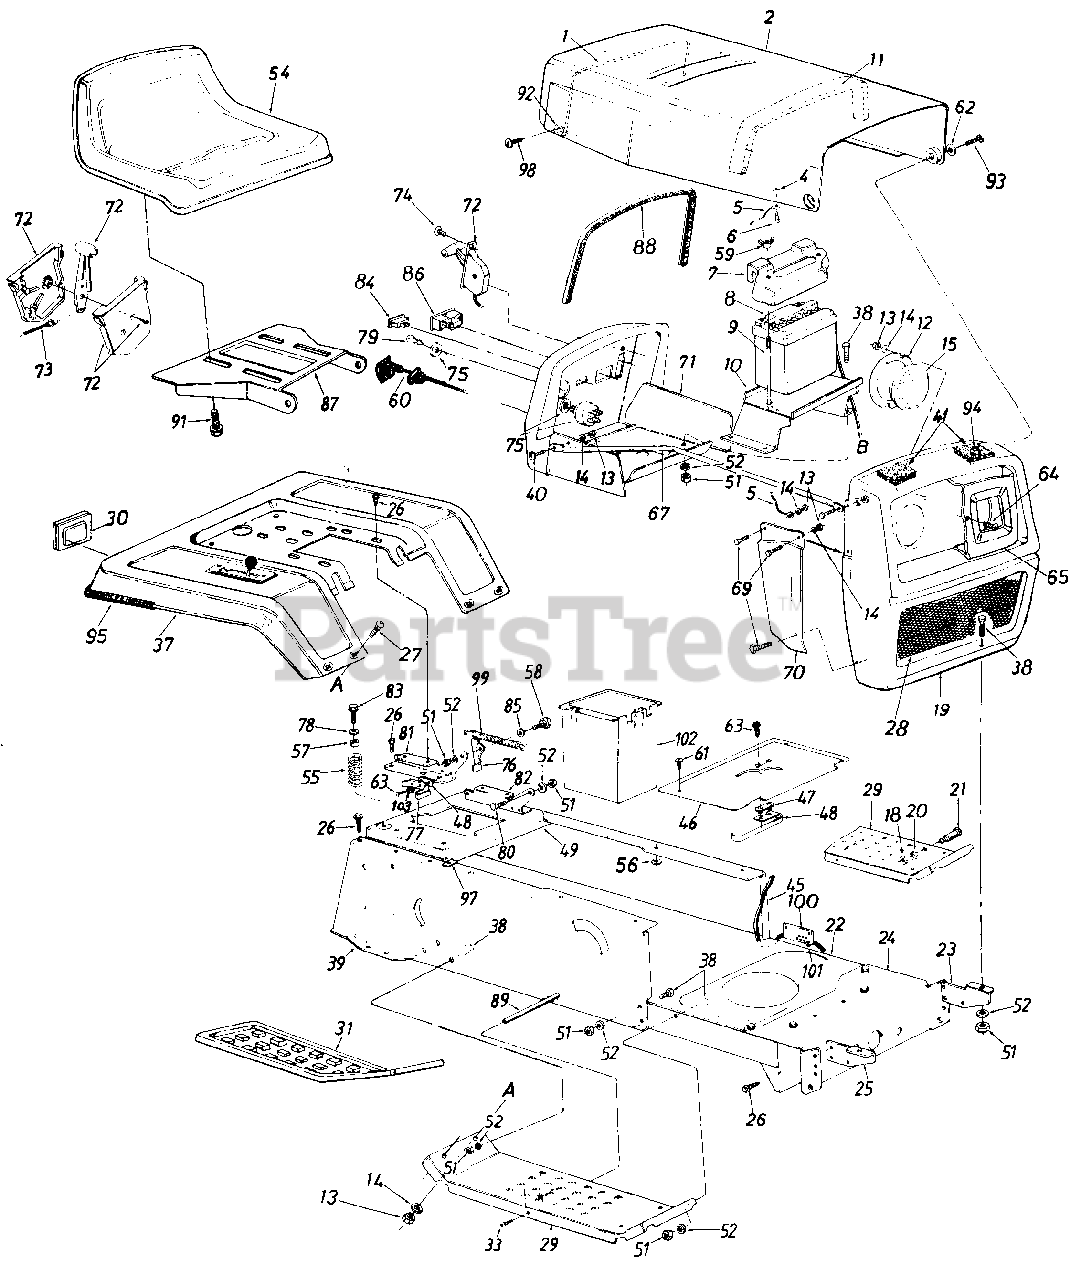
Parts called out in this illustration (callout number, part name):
1	Hood Spring
5	Hood Stop 7" Lg.
6	Pop Rivet
7	Battery Cover
8	12 Volt Battery
9	Battery Hold Down Rod
10	Battery Bracket
11	PVC Foam-Strip
12	Headlight Retainer
13	Hex Nut 14-20 Thd.
14	L-Wash 1/4" I.D.*
15	Headlight
18	Hex Nut 3/8-16 Thd.*
19	Grille Ass'y.
20	L-Wash. 3/8" I.D.*
21	Shld. Bolt .50" Dia. x .84
22	Lower Frame
23	Grille Mount Brkt.
24	Front Pivot Brkt.
25	Grille Mount Brkt.
26	Hex Wash. Hd. AB-Tap Scr. 5/16 x .75" Lg.
27	Carriage Bolt 1/4-20 x .5" Lg.*
28	Grille Insert
29	Running Board
30	Reflector
31	Foot Pad-L.H.
33	Truss Mach. Scr. 5/16-18 x .75" Lg.*
37	Fender
38	Hex Bolt 5/16-18 x .75" Lg.*
39	R.H. Side Frame
40	Hex Bolt 1/4-20 x .62" Lg.*
41	Foam Strip
45	L.H. Side Frame
46	Shift Cover
47	Reverse Safety Switch
48	Insulator Nut Plate
49	Hitch Plate
51	Hex Nut 5/16-18 Thd.*
52	L-Wash. 5/16" I.D.*
54	Seat Ass'y.
55	Compression Spring
56	Ext. L-Wash. 5/16" I.D.
57	Bushing
58	Shld. Bolt .437" Dia. x .268"
59	Wing Nut 1/4-20 Thd.-Plastic
60	Choke Control 46" Lg.
61	Truss Mach. Tap Scr. #10 x .50" Lg.
62	Washer .39" I.D. x .62" O.D.
63	Hex Wash. Hd. AB-Tap Scr. #8 x .50
64	Oval C-Sunk Mach. Scr. 1/4-20 x 1.5" Lg.
65	Bezel
69	Truss Hd. Scr. 1/4-20 x .75" Lg.*
70	R.H.-Grille Side Panel
73	Throttle Control Wire-35"
74	Truss Mach. AB-Tap Scr. #10 x .5" Lg.
75	Ignition Switch
76	Seat Lift Bracket
77	Spring Switch
78	Fl-Wash..344" I.D.
79	Ignition Key
80	Shld. Bolt .437" Dia. x .162"
81	Seat Pivot Brkt. Support-R.H.
82	Seat Pivot Brkt. Support-L.H.
83	Hex Hd. Tap Scr. 5/16-18 x 1 " Lg.
84	Light Switch
85	Spr-Wash. .445" I.D. x .75'1 O.D.
86	Ammeter
87	Seat Pivot Bracket
88	Molding Strip 27" Lg.
89	Running Board Rod
91	Hex Wash. Hd. Tap Scr. 3/8-16 x .75" Lg .
92	Hood Spring Retainer
93	Shld. Bolt .375 Dia. x .125
94	L-Nut 1/4-28 Thd.
95	Trim Strip 31.0" Lg.
97	Speed Nut #10Z
98	Self-Tap Scr. .5" Lg.
99	Extension Spring 5.31" Lg.
100	Brake Cable Bracket
101	Cable Tie
102	UtilitV Box
103	Fiber Washer
